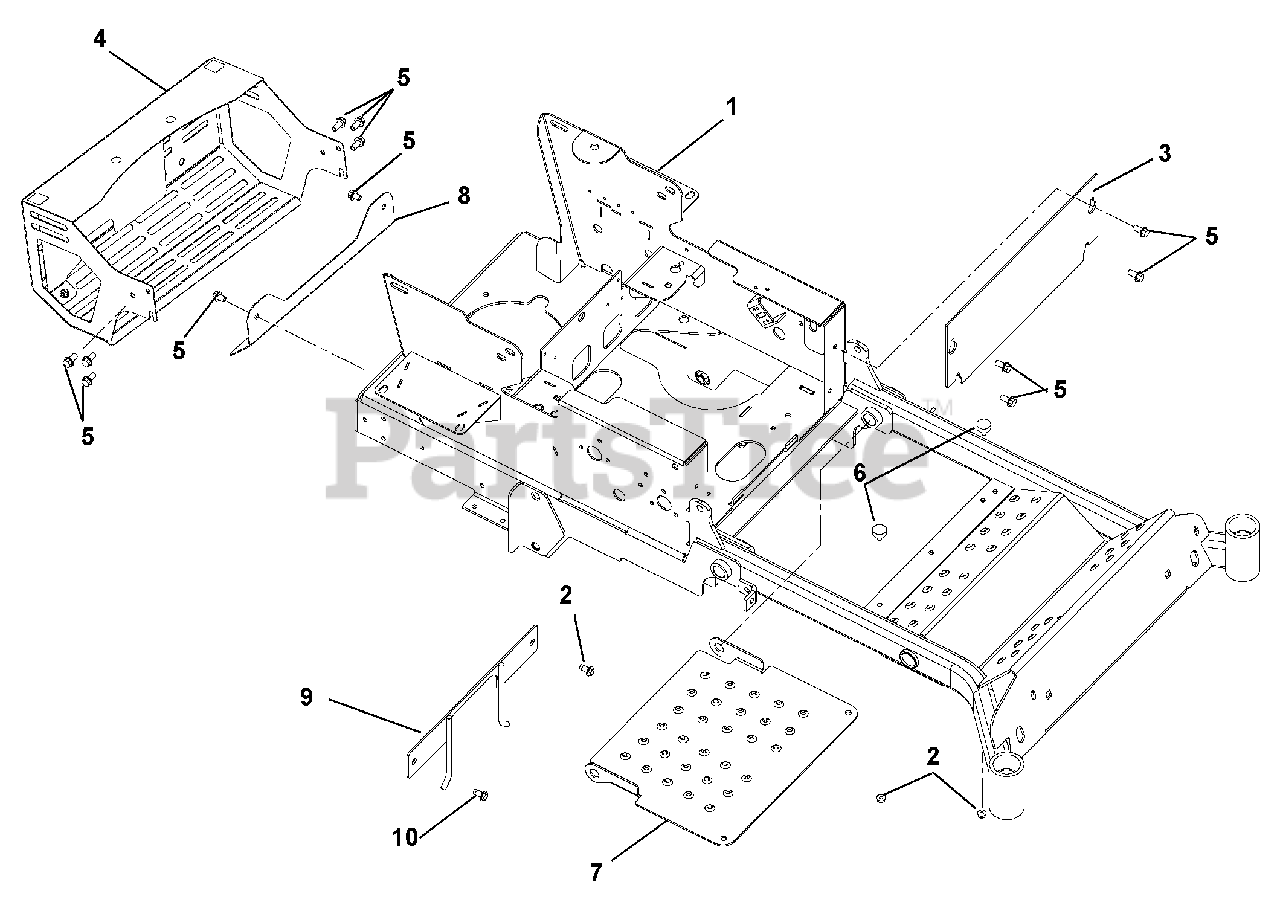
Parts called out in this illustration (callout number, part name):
1	Weldment, 44" – 48" HD Frame (991090, 082, 098, 099, 107, 108)
1	Weldment, 52" – 60" HD Frame (991083, 084, 100, 101, 109, 110)
2	Nut, Spin Lock Flange .312-18
3	Kick Plate
4	Kit, Bumper Gravely HD
5	Screw, Tapping .38-16 x .75 Hex Washer Head
6	Bumper, Rubber
7	Panel, Inspection
8	Bracket, Heat Shield — Muffler
9	Weldment, PTO Belt Finger
10	Screw, Tapping .38-16 x .75 Hex Washer Head Thread
